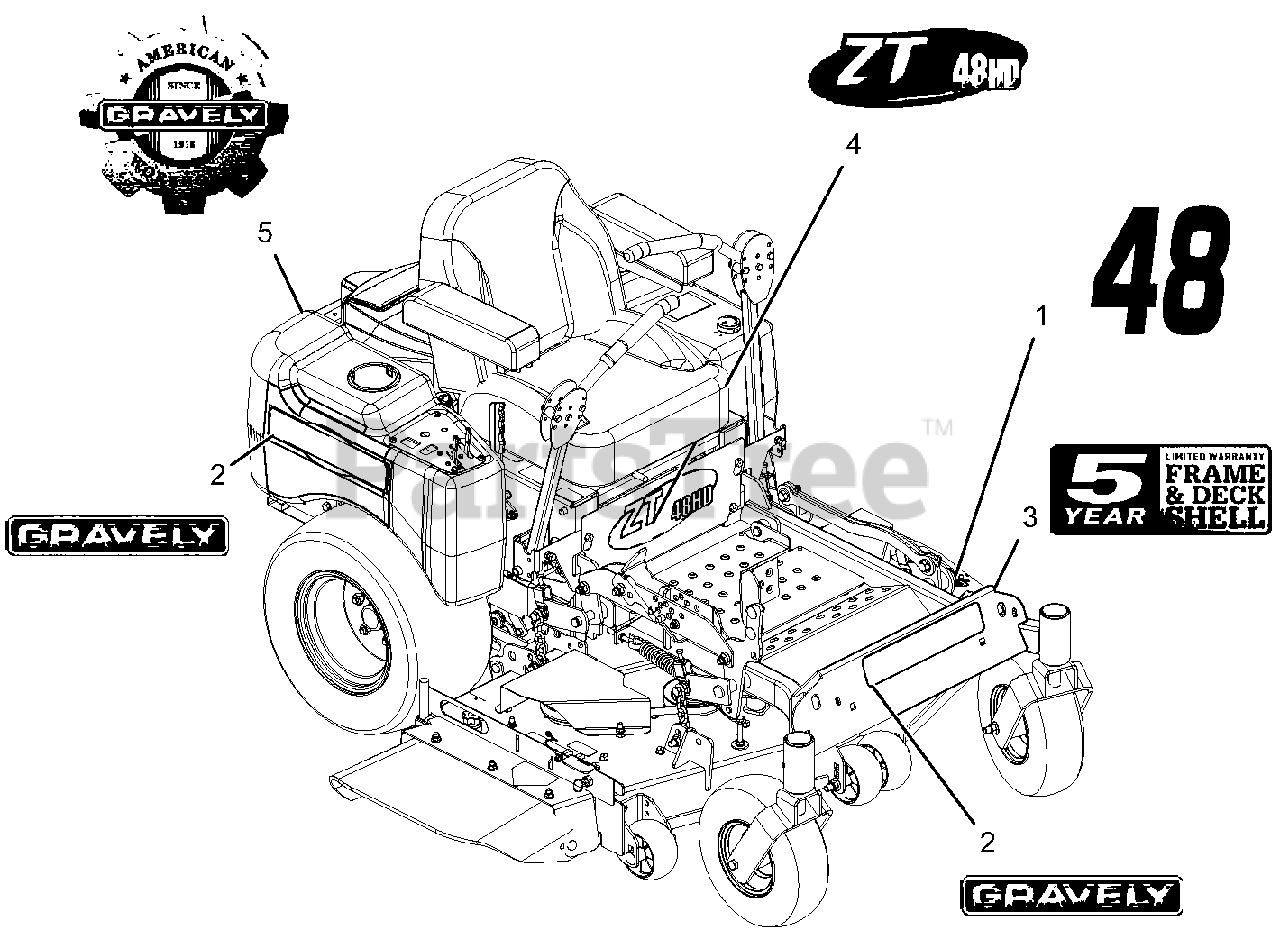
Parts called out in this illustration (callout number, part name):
1	DECAL, 48"
2	DECAL, FUEL TANK-GRAVELY
3	DECAL, DECK WARRANTY-FAB GRAVELY
4	DECAL, 48HD
5	DECAL, GRAVELY HERITAGE-SMALL
